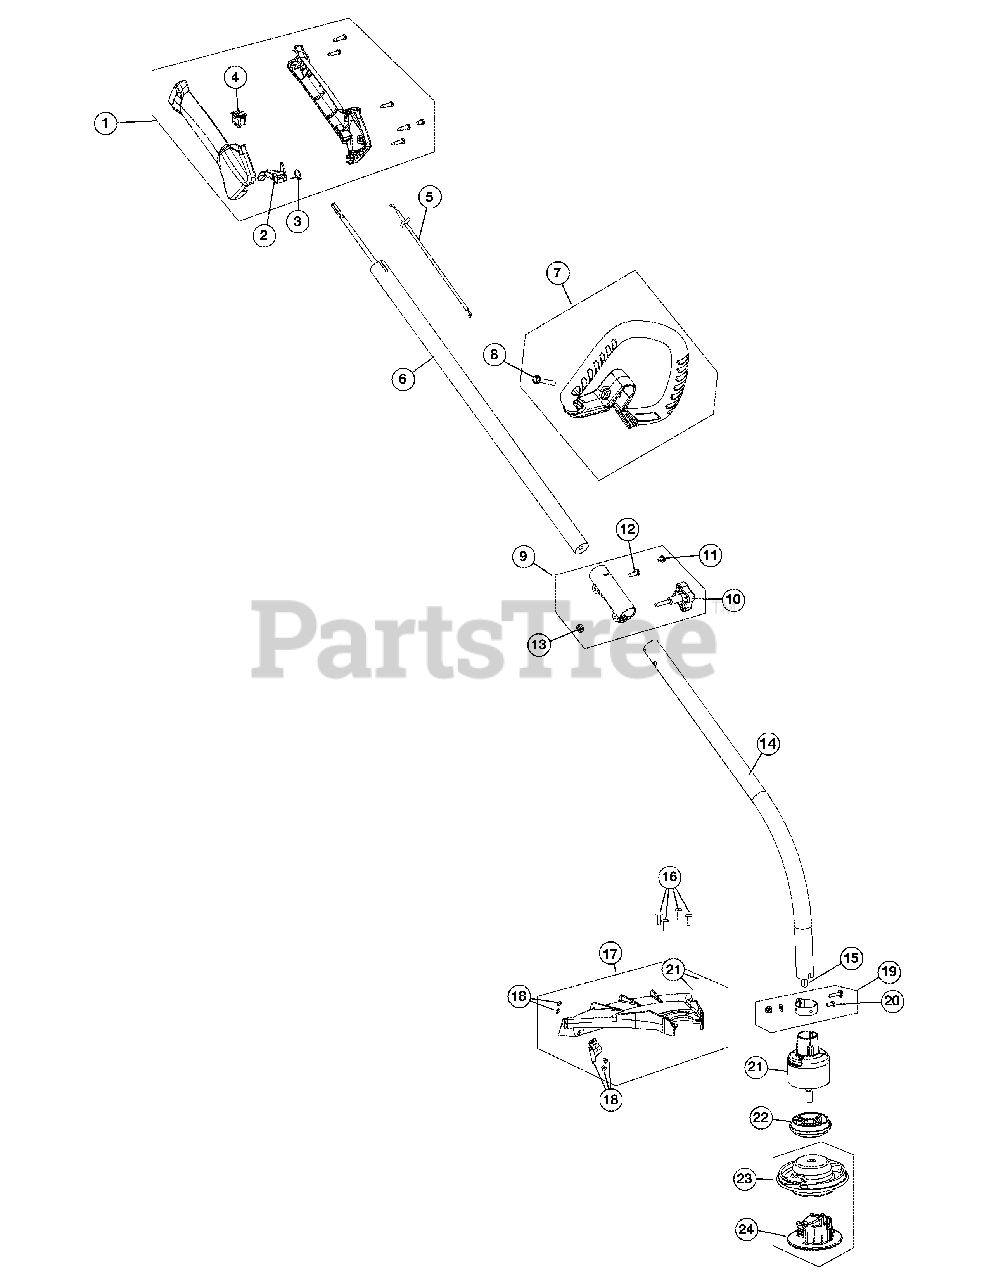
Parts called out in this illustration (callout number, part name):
1	Throttle Housing Assembly
2	Throttle Trigger
3	Throttle Trigger Spring
4	Switch Assembly
5	Throttle Cable Assembly
6	Upper Drive Shaft Assembly
7	D-Handle Assembly
9	Split Boom Coupler
10	Adjustment Knob
11	Coupler Anti-Rotation Screw
12	Coupler Bolt
13	Adjustment Knob Nut
14	Lower Drive Shaft Housing
15	Lower Flexible Drive Shaft
16	Shield Mount Screw Assembly
17	Shield Assembly
18	Blade Assembly
19	Lower Clamp Assembly
20	Anti-Rotation Screw
21	Bushing Housing Assembly
22	Adapter
23	Cutting Head Assembly
24	Cutting Head Cap
